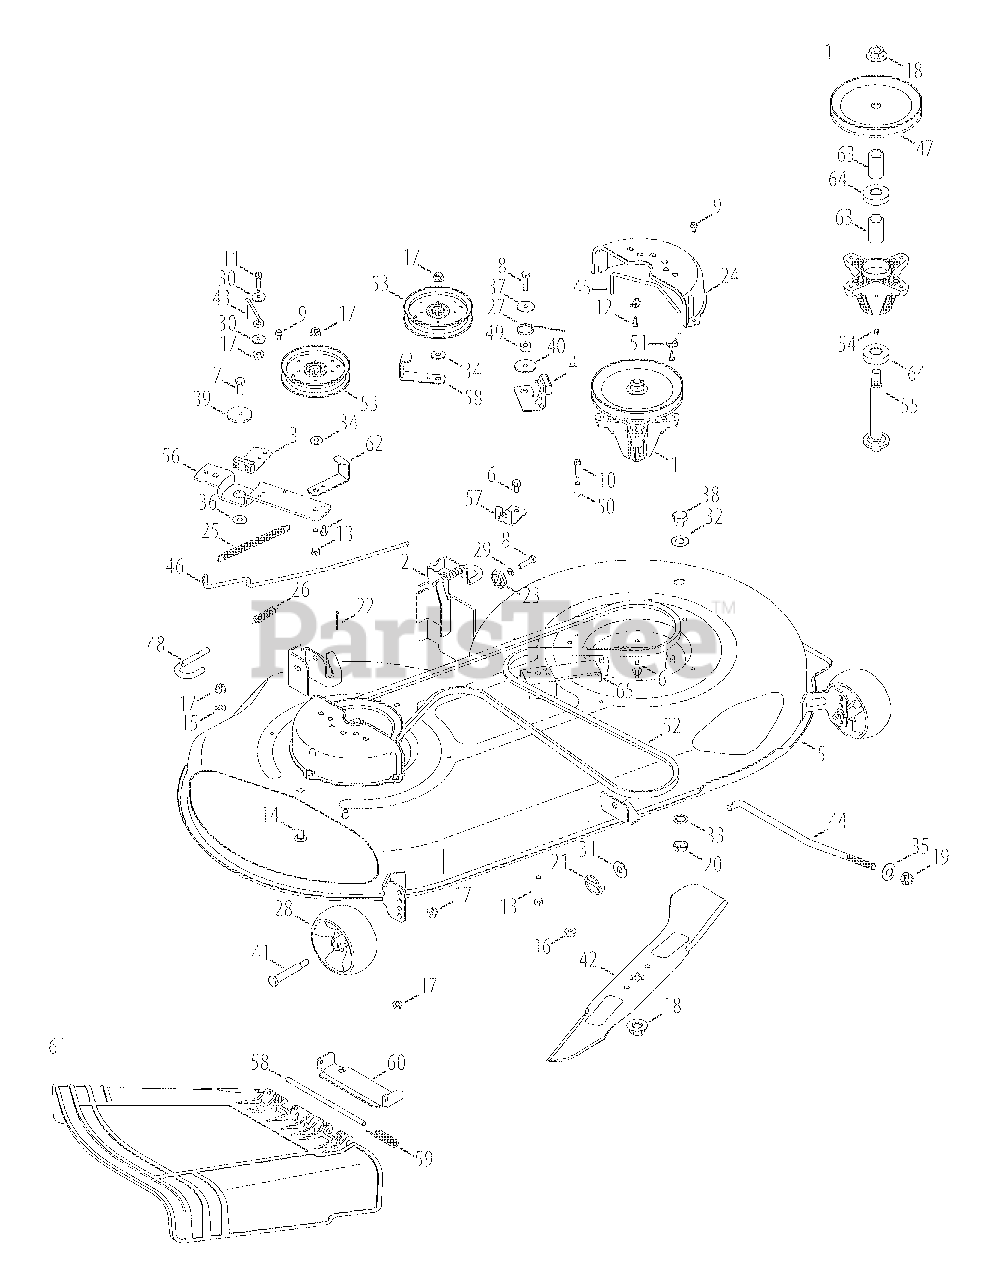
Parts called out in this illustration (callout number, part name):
1	Spindle Ass’y, Pulley, 6.93 Dia
2	Bracket Ass’y, Deck, Hanger LH
3	Brake Ass’y, Deck
4	Brake Ass’y, Deck
5	Deck Ass’y, Offset
6	Screw, Self-tapping, 5/16-18, .750,
7	Hex Screw, 3/8-16, 1.00, Gr5, Std
8	Hex Screw, 5/16-18, 1.25, Gr5, Std
9	Screw, Self-tapping, 1/4-20, 0.500,
10	Screw, Self-tapping, 1/4-20, 1.500,
11	Screw, Self-tapping, 1/4-20, 1.250,
12	Screw, #10-16:.625
13	Hex Screw, 3/8-16, 2.00, Gr5, Std
14	Bolt, Carriage, 3/8-16, 0.75, Gr1
15	Nut, Push, 3/8
16	Nut, Flange Lock, 5/16-18, Grf,
17	Nut, Flange Lock, 3/8-16, Grf,
18	Nut, Flange, 5/8-18
19	Nut, Lock, 1/2-13
20	Nut, Hex, M16-1.5
21	Pin, Lynch, .1875
22	Pin, Cotter, 1/8 x 1.25
23	Gear, Deck, Adjustment
24	Belt Cover
25	Spring, Extension, .62 Dia x 6.12
26	Spring, Comp, .535 OD x 1.751
27	Spring, Torsion, .992 I.D x 1.17 O.D
28	Wheel, Deck, 5.0 Dia Ball
29	Washer, Lock, 5/16, Regular Duty
30	Washer, Flat, .265 x .938 x .120
31	Washer, Flat, .531 x 1.25 x .100
32	Washer, Flat, .64 x 1.24 x .06,
33	Washer, Lock, 5/8, Int Tooth
34	Washer, Flat, .385 x .870 x .092
35	Washer, Bell, .63 x 1.25 x .18
36	Washer, Flat, .385 x 1.0 x .030
37	Washer, Flat, .330 x 1.25 x .06,
38	Plug, Bolt, M16 x 1.5
39	Spacer, Shoulder, .8840 x .190
40	Spacer, Shoulder, .5000 x .1475
41	Bolt, Shoulder, .496 x 2.50, 3/8-16
42	Blade
43	Rod, Keeper, Belt
44	Rod, Lift, Deck, Frt, 13.7
45	Rod, Keeper, Belt
46	Rod, Control, Brake
47	Pulley, Deck, 6.93 Dia
48	Rod, Handle, Deck Release
49	Spacer, .315 x .750 x .375
50	Spacer, .260 x .375 x 1.030
51	Clamp, Casing
52	Belt, V-Type
53	Pulley, Idler, 4.25"Dia
54	Fitting, 3/16, Lnc#70, Drive Lube
55	Shift, Spindle, 6.11.
56	Bracket, Idler, Pivot
57	Bracket, Cable, Deck Engage
58	Pin, Hinge, Dia .3125 x 7.96
59	Spring, Torsion, .44 I.D. x 2.0
60	Bracket, Chute
61	Chute Ass’y, Deflector
62	Guard, Belt
63	Spacer, .792 x 1.060 x 1.86
64	Bearing, Ball
65	Bracket, Idler Support
